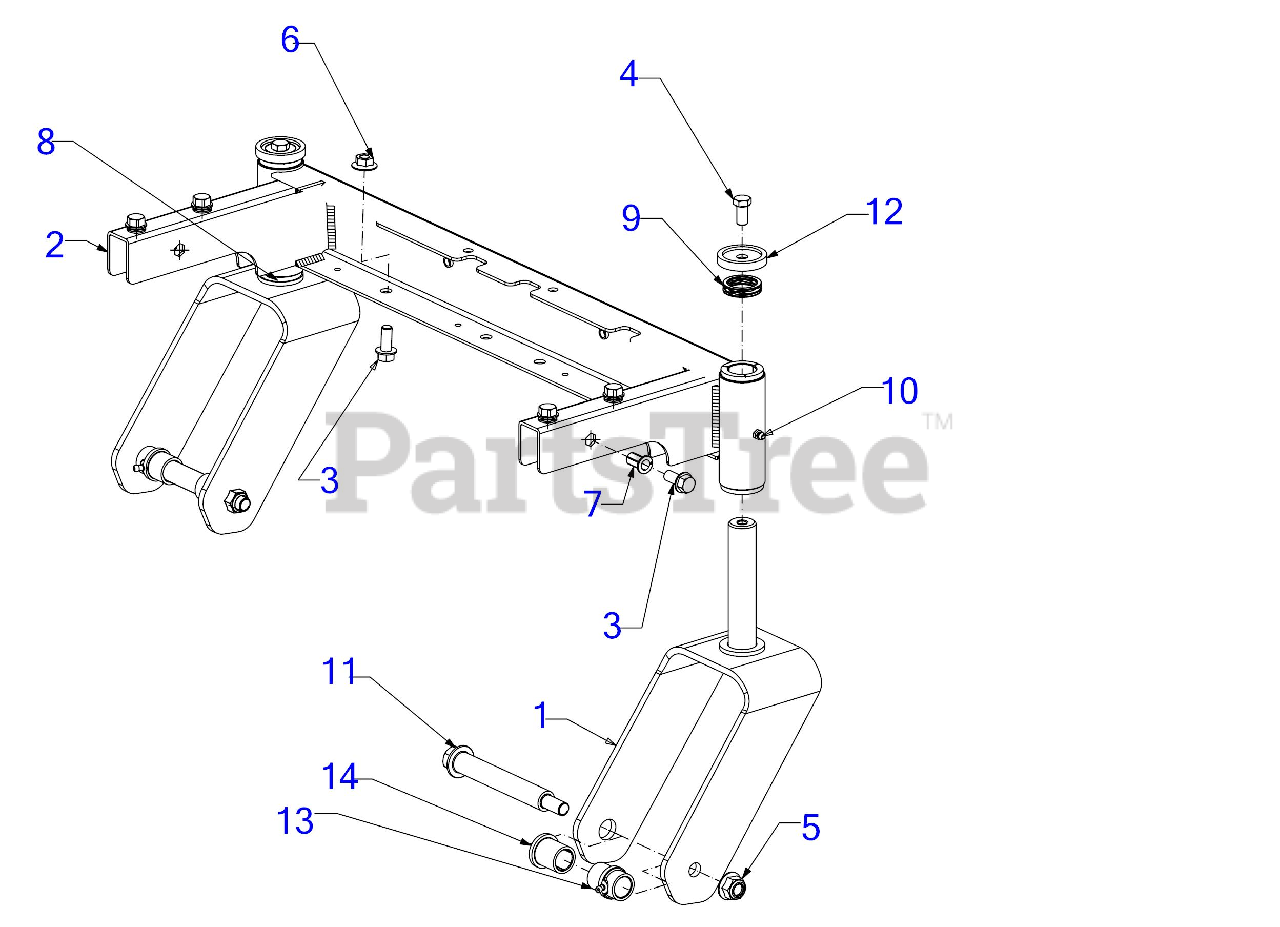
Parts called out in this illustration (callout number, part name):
3	SCREW 3/8-16 x .875 GR5
4	SCREW 3/8-16 x .75 GR 5
6	FLANGE LOCK NUT
7	NUT RIVET
8	FLANGE BEARING 25MMIDX1.25OD
9	WAVE WASHER
10	GREASE ZERT 1/4-28
11	SHOULDER BOLT 1.00X4.75X1/2-13
12	SHOULDER SPACER 1.75 OD
13	FLANGE BEARING W/ZERT
14	FLANGE BEARING .760IDX1.00OD
